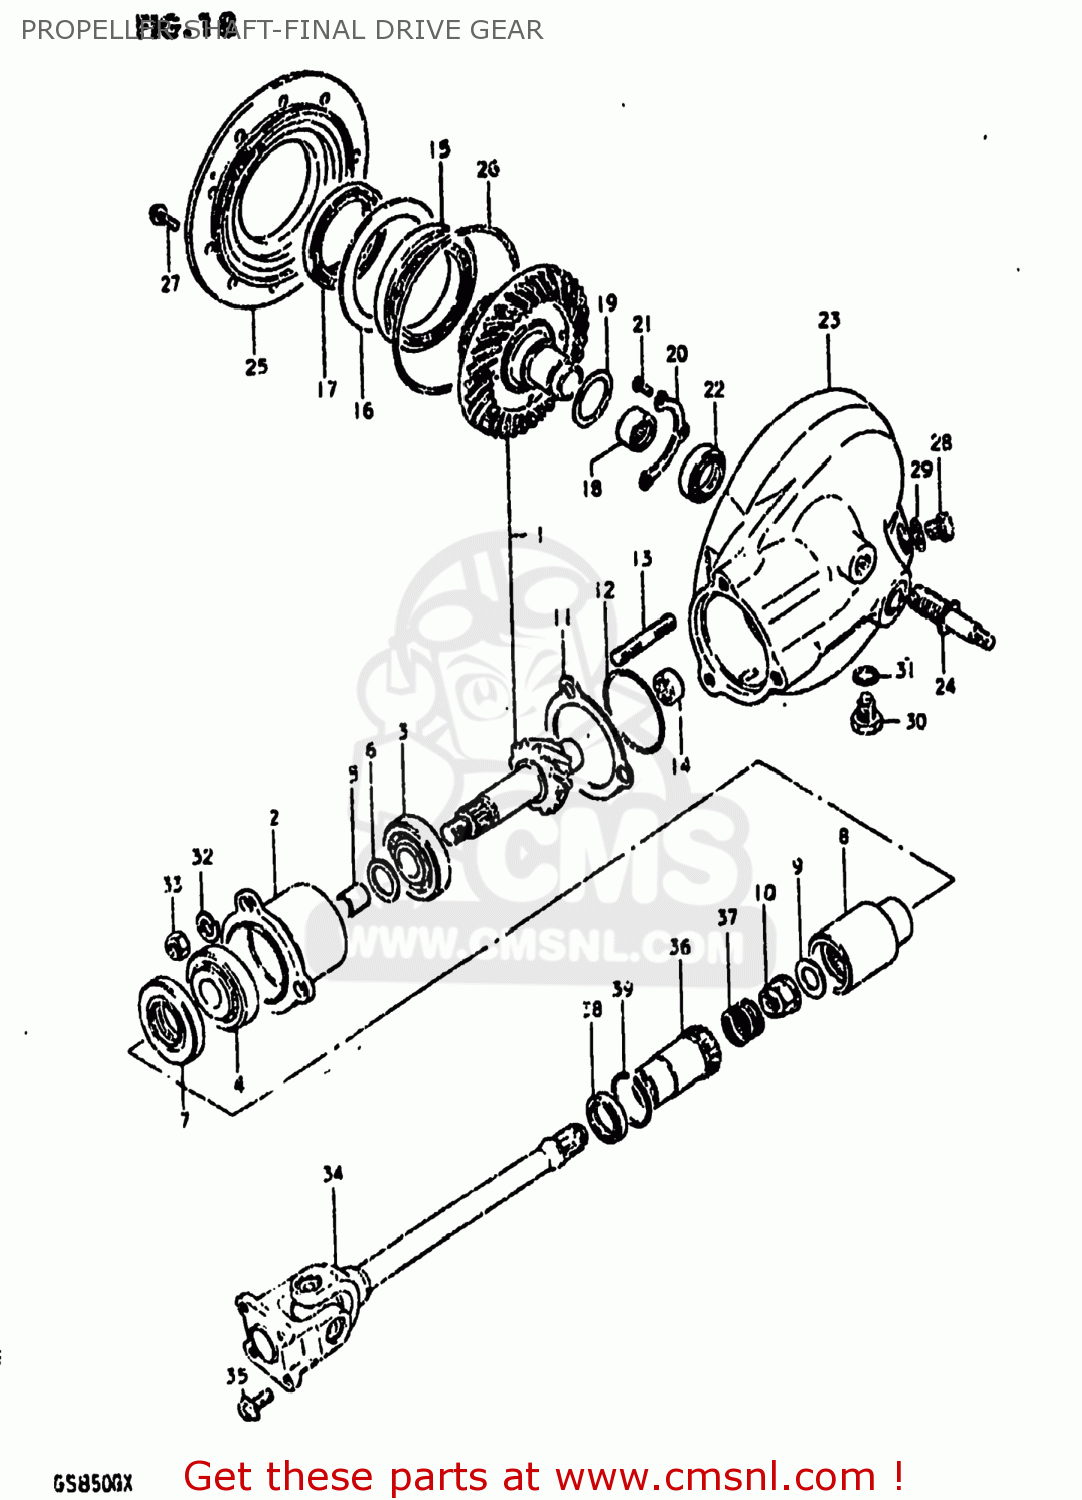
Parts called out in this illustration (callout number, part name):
0	FINAL BEVEL GEAR & CASE
1	GEAR SET,FINAL BEVEL
2	HOUSING,DRIVE GEAR
3	BEARING(25X52X19.25)
4	BEARING
5	SPACER (25.2X30X3.5)
6	SHIM (25X30X2
7	SEAL,OIL(32X54X7)
8	GEAR,FINAL DRIVE
9	WASHER(14X29X4)
10	NUT
11	SHIM,DRIVE GEAR HOUSING
12	O RING(D:2.4,ID:62.6)
13	STUD 10X30
14	BEARING(24X33X17)
15	BEARING(70X110X13)
16	SHIM,DRIVEN GEAR BEARING
17	SEAL,OIL(70X96X16)
18	BEARING(35X48X23.7)
19	SHIM,FINAL DRIVEN GEAR
20	RETAINER,FINAL DRIVEN GEAR BRG
21	SCREW 6X12
22	SEAL,OIL(30X42X7)
23	CASE ASSEMBLY,FINAL GEAR
24	STUD
25	CASE,FINAL GEAR BEARING
26	O-RING (D:3.1 ID:144.4)
27	BOLT
28	PLUG (14X12)
29	GASKET(14X19.2X2) (NAS)
30	PLUG
31	GASKET(14X19.2X2) (NAS)
32	LOCK WASHER
33	NUT
34	SHAFT ASSEMBLY,PROPELLER
35	BOLT 8X16
36	COUPLING,PROPELLER SHAFT
37	SPRING
38	SEAL,OIL(30X40.5X5.5)
39	CIRCLIP
